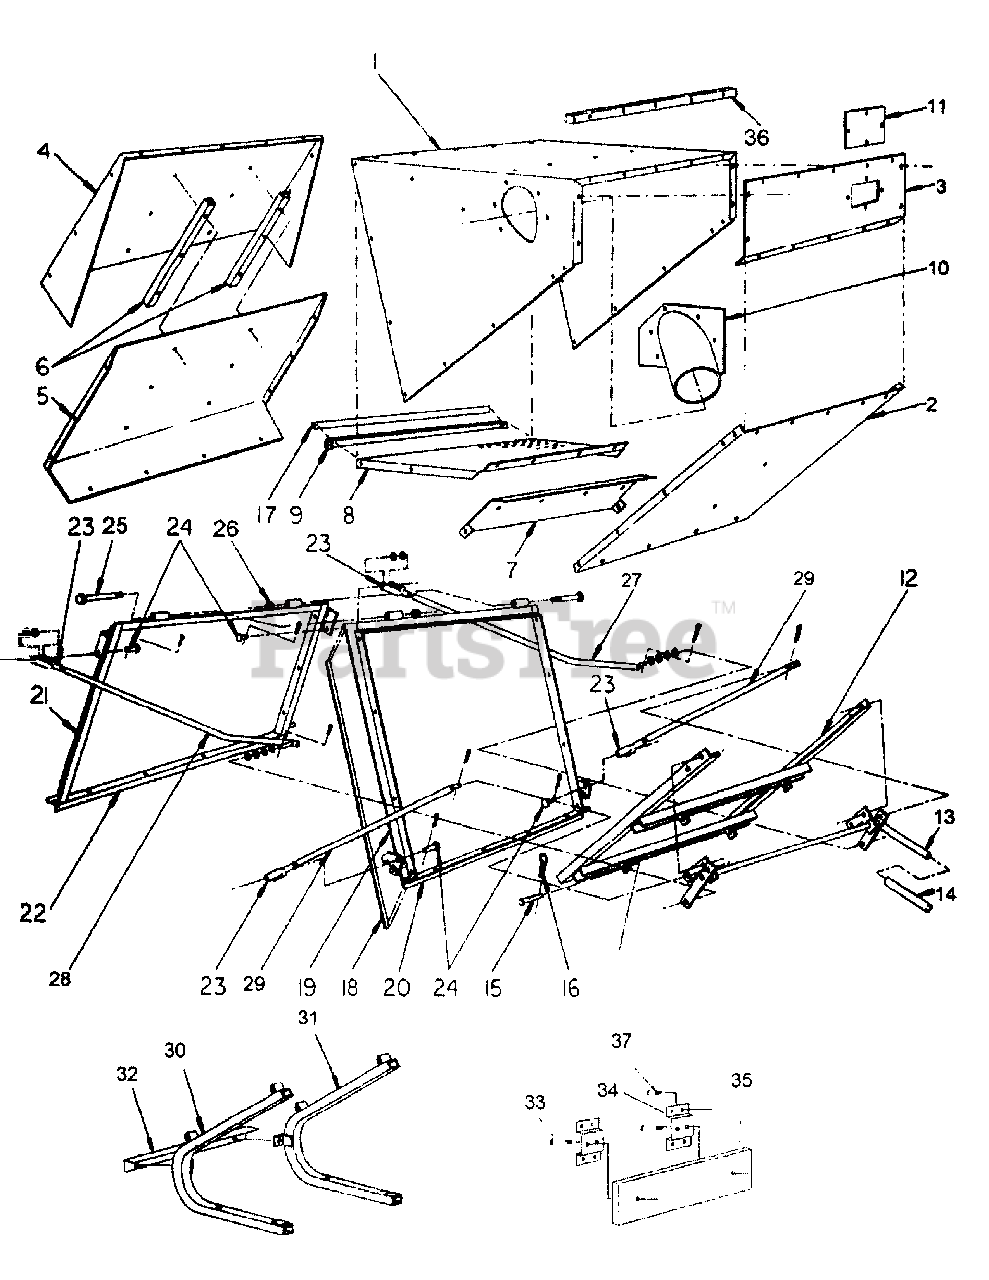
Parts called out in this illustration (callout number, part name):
1	CATCHER BODY
2	CATCH BOX BOTTOM
4	OUTER DOOR SHELL
5	INNER DOOR SHELL
6	DOOR VENT TUBING
7	INTAKE DEFLECTOR
8	SCREEN
9	REAR SCREEN SUPPORT
10	6" INTAKE TUBE
11	5" X 6.5" ACRYLIC
12	CATCHER FRAME BASE
13	LEVER DUMP ASSEMBLY
14	5" VINYL GRIP
15	1/2" X 4" ADJUSTABLE CLEVIS
16	.091 X 2.0 HAIR SPRING COT
17	RUBBER SEALS
18	FOAM SEAL
19	CATCHER OPENING FRAME
20	BOTTOM CATCHER OPENING FRAME
21	CATCHER DOOR FRAME
22	BOTTOM DOOR FRAME
23	3/8" -24 ADJUSTABLE YOKE END
24	3/8" X 1" CLEVIS PIN
25	1/2" X 5" HEX HEAD BOLT
26	1/2" NYLOCK NUT
27	LEFT HINGE ROD
28	RIGHT HINGE ROD
29	LATCH ROD
30	RIGHT CATCHER MOUNTING FRAME
31	LEFT CATCHER MOUNTING FRAME
32	CATCHER MOUNTING FRAME BUMPER
33	3/8" X 4-1/2" X 16 HEX HEAD BOLT
34	WEIGHT MOUNTING BRACKET
35	WEIGHT BAR
36	FRONT BUMPER
37	5/16"-18 X 1" CARRIAGE BOLT
